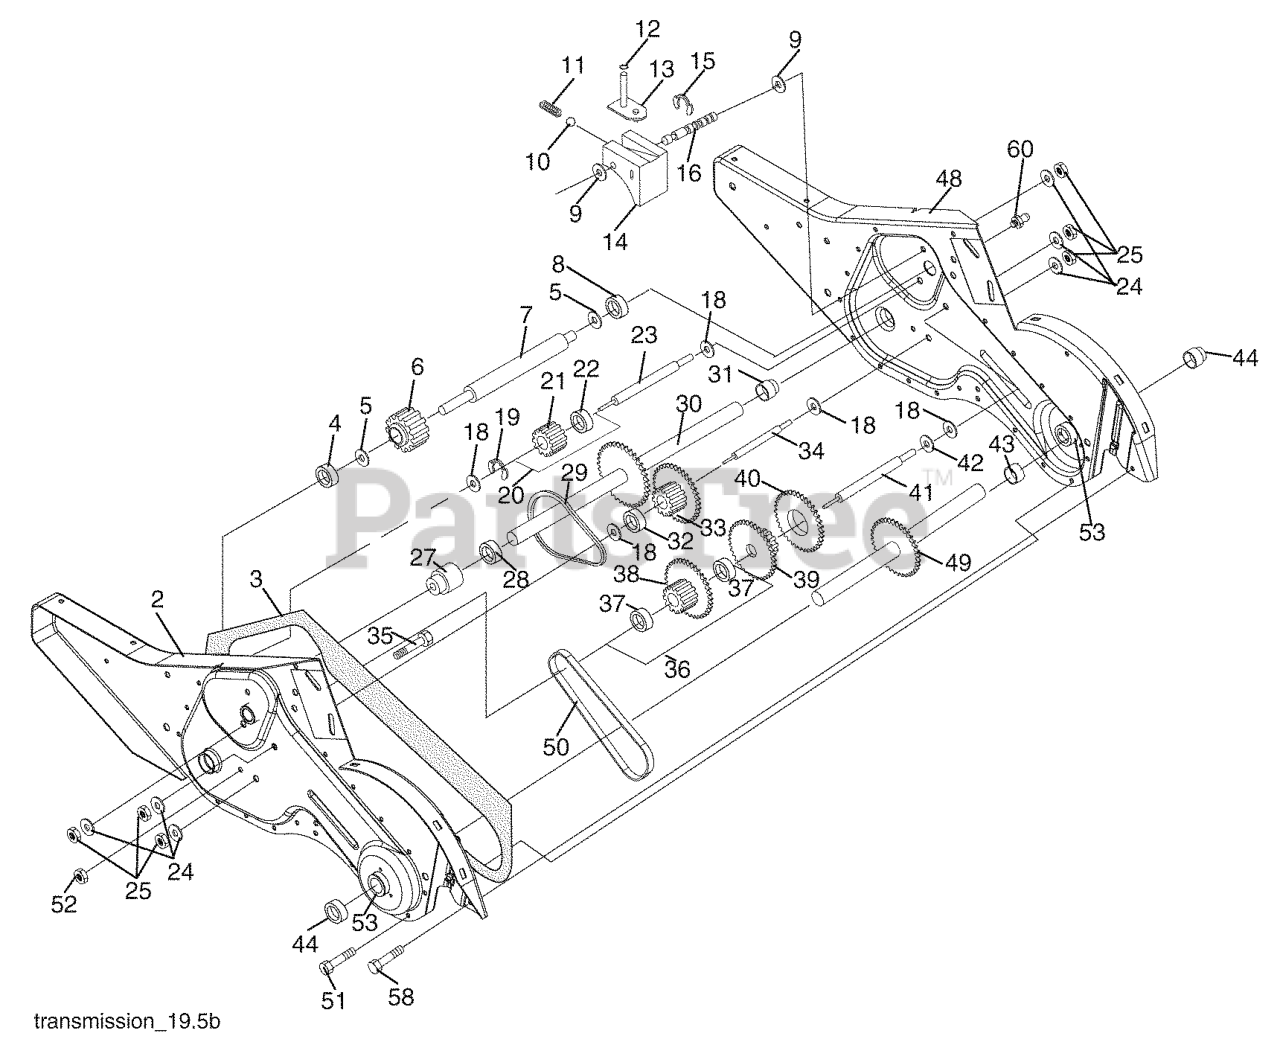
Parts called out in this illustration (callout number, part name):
1	TRANSMISSION ASM.
2	GEARCASE.ASM.CRT.LH.W/BEARING
3	GASKET
4	NEEDLE BRNG LT
5	THRUST WASHER
6	GEAR.PINION.INPUT
7	SHAFT.INPUT."D".TILLER
8	BEARING TI
9	WASHER, SEAL (2 2)
10	STEEL BALL KIT
11	SPRING-SHIFT CRT
13	BRACKET ASM.SHIFT.CRT
14	SHIFT FORK TI
16	SHAFT.SHIFTER.TILLER
20	GEAR ASSY CRT
21	GEAR-REV IDLR CRT
22	NEEDLE BEARING TI
24	LOCKWASHER
25	NUT.ASF.HEX.7/16
27	BEARING, SHAFT LH CRT
30	GROUND SHAFT ASS'Y
31	BEARING, SHAFT RH CRT
33	SPRCKT 8 GEAR CRT
34	SHAFT.SECONDARY.REDUCTION.CRT
35	SCRW WHIZ LOK CRT
36	SPROCKET.ASM.W/BEARING.TILLER
37	BEARING
38	SPROCKET, TINE
41	SHAFT.REDUCTION.TILLER
42	BRNG RACE T
44	SEAL ASM, OIL
48	GEARCASE.ASM.CRT.RH.W/BEARING
49	TINE SHAFT
50	CHAIN.TILLER
51	SCREW
52	NUT
53	KIT.BEARING.TILLER.
58	BOLT SHOULDER 1/4-20 UNC X.875
60	FITTING.GREASE.TAPERED
